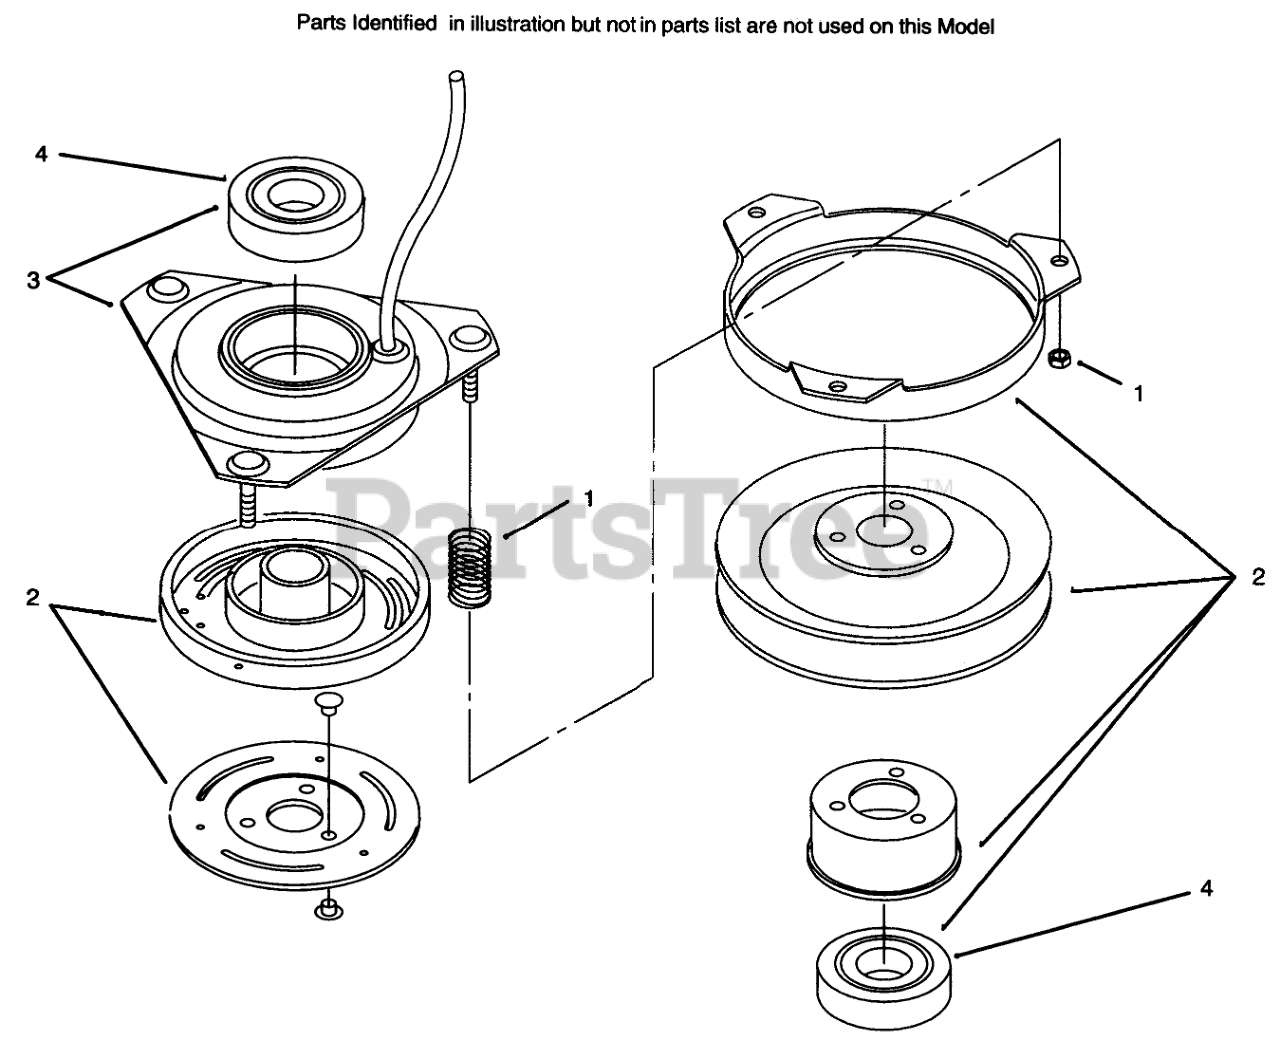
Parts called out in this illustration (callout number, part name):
1	ACCESSORY PKG SRVC PART
2	ASM - ROTOR/ARMATURE
3	FIELD ASSY (SRVC PART)
4	BEARING-ELEC CLUTCH
